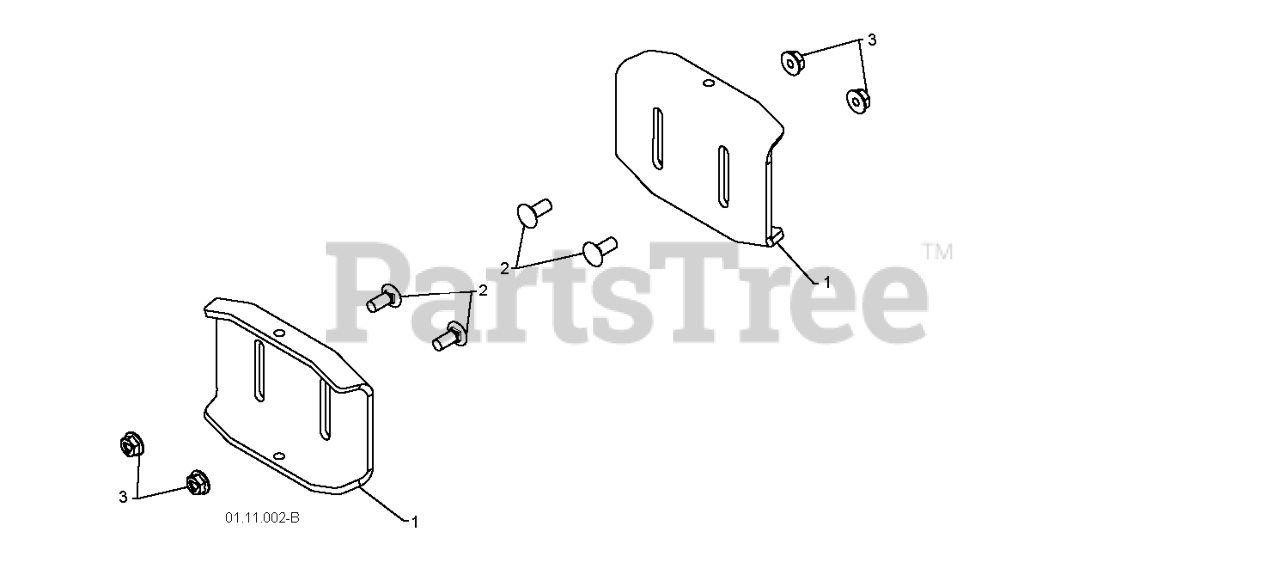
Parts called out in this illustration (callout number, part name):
1	PLATE.SKID.HEAVYDUTY.BLACK
2	BOLT
3	NUT.LOCK.5/16-18
